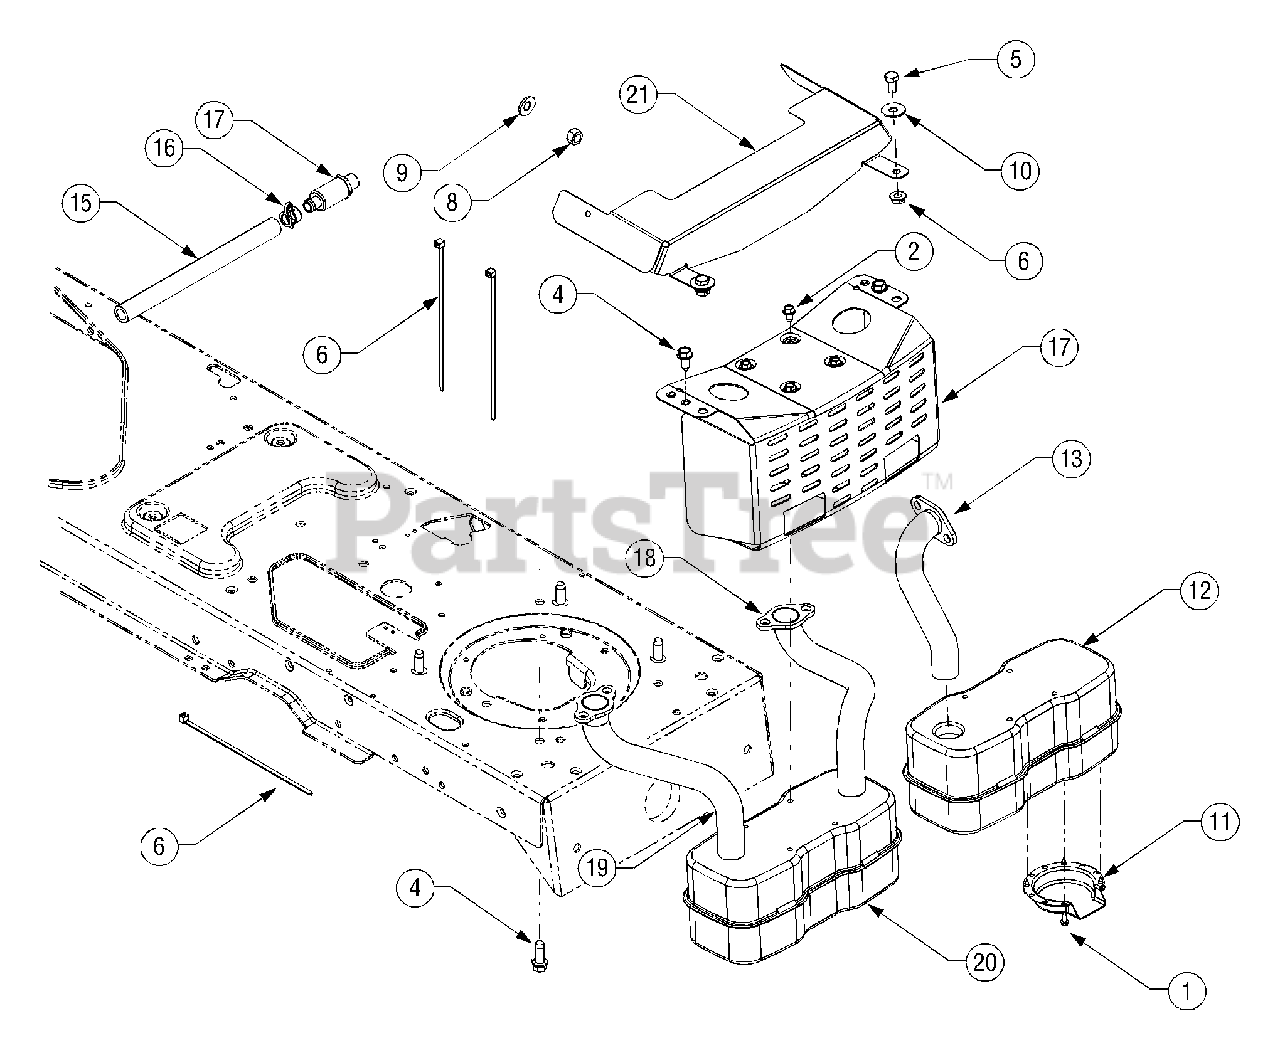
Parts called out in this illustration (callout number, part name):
1	Screw, #8-18, 0.500
2	Screw, Hex, 1/4-20, 0.500
4	Screw, Hex, 5/16-12 x .75
4	Screw, Hex, 3/8-16 x 1.00 (LT1042 & LT1045)
4	Screw, Hex, 3/8-16 x 1.25 (LT1046 & LT1050)
5	Screw, Hex, 5/16-18 x .625 (LT1046 & LT1050)
6	Cable, Tie, 3/16 x .05 x 7.4
7	Nut, Flange Lock, 5/16-18 (LT1046 & LT1050)
8	Hex Nut, 3/8-16 (LT1046 & LT1050)
9	Lock Washer,.406 x.875 x.059 (LT1046 & LT1050)
10	Washer, Flat, .349 x 1.00 x .063 (LT1046 & LT1050)
11	Deflector, Muffler
12	Muffler, Single Inlet (LT1042 & LT1045)
13	Pipe, Exhaust (LT1042 & LT1045)
15	Extension Hose, Oil Drain
16	Cap, Oil Drain
17	Drain, Oil
18	Pipe, Exhaust, LH (LT1046 & LT1050)
19	Pipe, Exhaust, RH (LT1046 & LT1050)
20	Muffler, Dual Inlet (LT1046 & LT1050)
21	Shield, Heat (LT1046 & LT1050)
